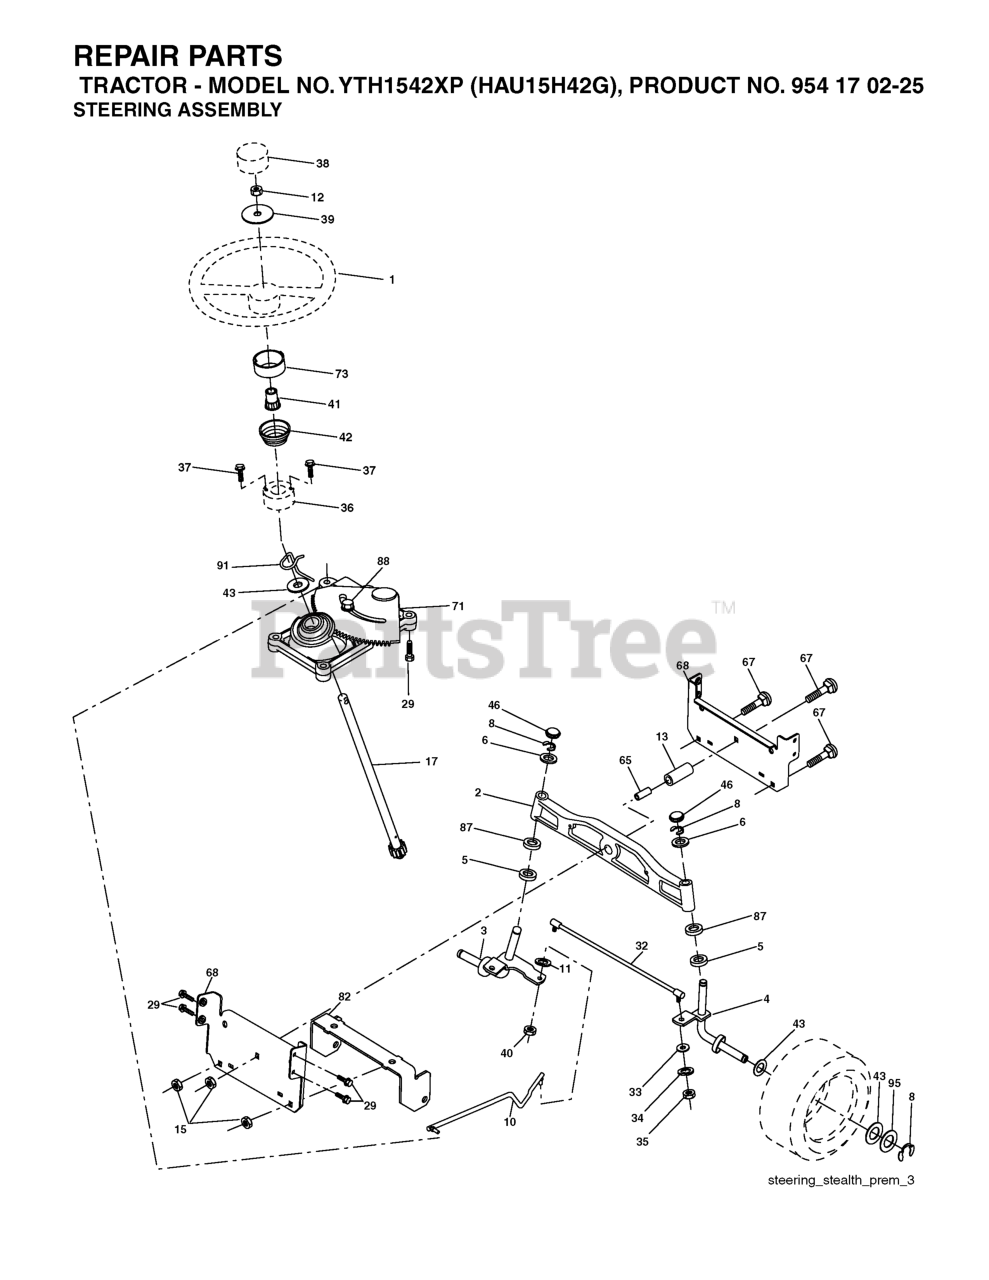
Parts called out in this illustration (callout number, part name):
1	STEERING WHEEL
2	AXLE ASSY FRONT
3	SPINDLE.ASM.LH.15"TIRES
4	SPINDLE.ASM.RH.15"TIRES
5	THRUST WASHER
10	DRAGLINK.15".TIRES.2001
11	WASHER, LOCK 3/8
12	NUT.HEX.1/2-20
13	TUBE, PIVOT AXLE
15	NUT
17	SHAFT ASM STRG
29	SCREW, 3/8-16X3/4
33	WASHER M
34	WASHER.LOCK.HVY.HLCL.SPR.5/16
35	NUT, CROWNLOCK
36	BUSHING, STRG. BLK
37	SCREW.TT.#10-32X.5.3/8.FLANGE
38	CAP.WHEEL.STEERING.GREY
39	Washer 9/16 ID x 1 1/2 OD 11 Ga. Zin
40	NUT CROWNLOCK 3/8-24
41	STEERING WHEEL ADAPTOR
46	CAP.SPINDLE.BLACK
65	SPACER BRACE AXLE
67	BOLT CARRIAGE
68	BRACE.AXLE.15"TIRES
71	STEERING ASM
73	EXTENSION STEERING PREMIUM
82	BRACKET
87	WASHER, FLAT .781 X 1 1/2"
88	BOLT, SHOULDER 7/16-20
91	CLIP.STEERING
95	WASHER.HARDENED
